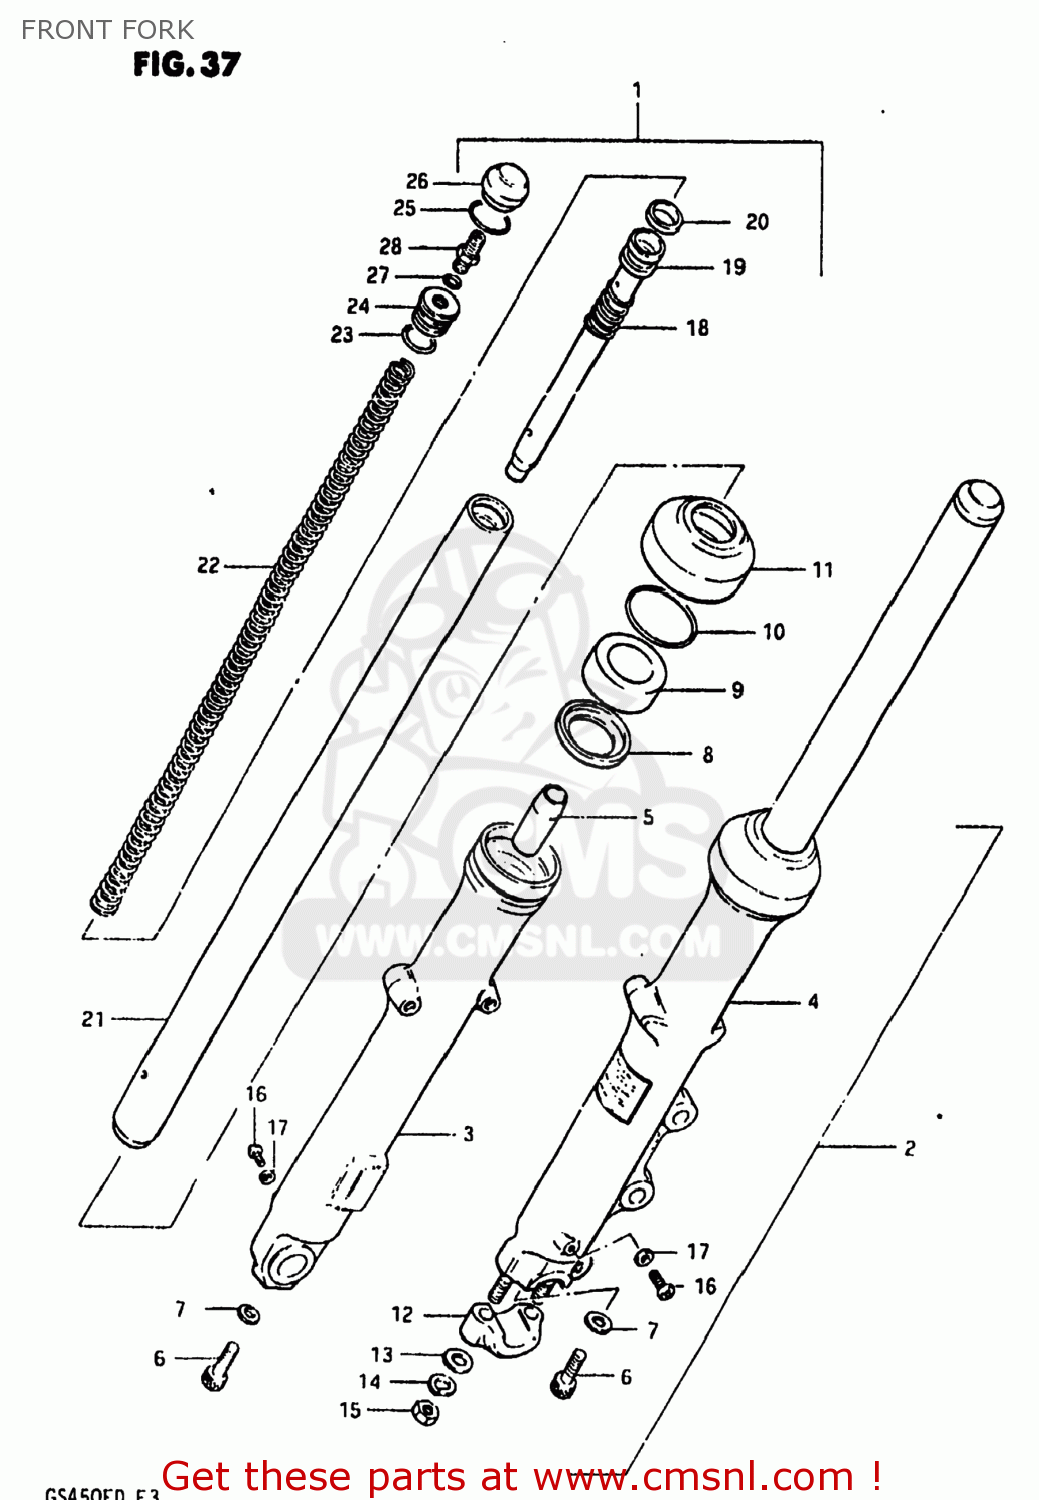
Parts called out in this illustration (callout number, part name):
1	DAMPER ASSEMBLY,RIGHT
2	DAMPER ASSEMBLY,LEFT
3	TUBE,FORK,OUTER,RIGHT
4	TUBE,FORK,LEFT,OUTER
5	PIECE,OIL LOCK
6	BOLT(8X27)
7	GASKET (NAS)
8	SPACER,OIL SEAL
9	OIL SEAL,FRONT FORK
10	RING,OIL SEAL STOPPER
11	DUST SEAL
12	HOLDER,AXLE
13	WASHER
14	LOCK WASHER
15	NUT
16	SCREW 4X6
17	GASKET (NAS)
18	SPRING,REBOUND
19	CYLINDER,FRONT FORK
20	RING,PISTON
21	TUBE,FORK,INNER
22	SPRING
23	O RING
24	SEAT,SPRING
25	RING,STOPPER
26	CAP,FRONT FORK
27	O-RING
28	VALVE,AIR
